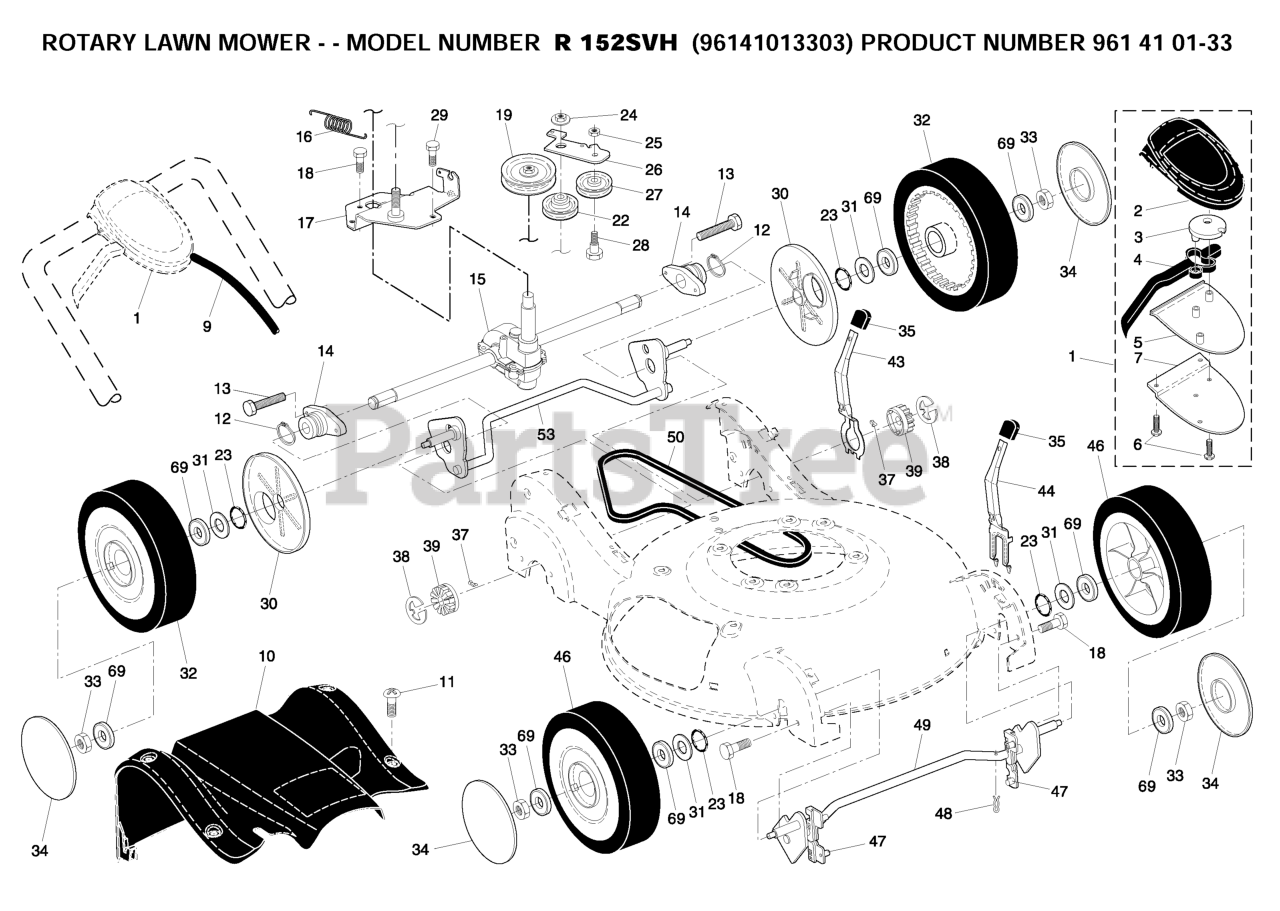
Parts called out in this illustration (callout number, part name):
2	COVER TOP AUTO WALK CONTROL
3	PULLEY.CAM.DRIVE.CONTROL.HV
4	LEVER
5	COVER BOTTOM AUTO WLK CONTROL
6	SCREW, PHILLIPS HEAD 10 X 5/8
7	BRACKET.DRIVE.CONTROL.MOUNT.BL
9	ASM.CABLE.
12	RETAINING RING (2 2)(3 2)
13	SCREW.1/4-20X21/4.HEX.
14	BEARING / AXLE SUPPORT
15	TRANSMISSION.21.HV.RWGD.AW/EZ
17	BRACKET, GEAR CASE / DRIVE
19	RP PULLEY.DRIVE.EZ
22	PULLEY.IDLER.V-BELT
23	O-RING..070X.487.NEOPRENE
24	NUT.HEX.FLANGE.3/8-16.LOCKNUT
25	NUT.CENTERLOCK.5/16-
26	ARM.IDLER.BZP
27	IDLER PULLEY
28	SHOULDER BOLT
29	SCREW 14-20 X 5/8
30	DUST COVER, WHEEL
31	WASHER.FLAT.1/2
32	WHEEL.9X2.25.LP.TIGER.BLACK
33	NUT.HEX.FLANGE.3/8-16.LO(3 2)
34	HUBCAP.WHEEL.5.SPOKE.SILVER
37	PAWL, DRIVE
38	E-RING 7/16 RE
39	PINION.14.TEETH.FGD
43	LEVER, SELECTOR, HEIGHT, REAR
44	LEVER, SELECTOR, HEIGHT, FRONT
46	WHEEL.9X2.25.LP.TIGER.BLK
47	BUSHING.FRONT.TORQUE.SHAFT
48	SPRING RETAINER
49	SHAFT FRONT
50	BELT, DRIVE
53	SHAFT.ASM.REAR.TORQUE.HV.BZP
69	BEARING.8".WHEEL
